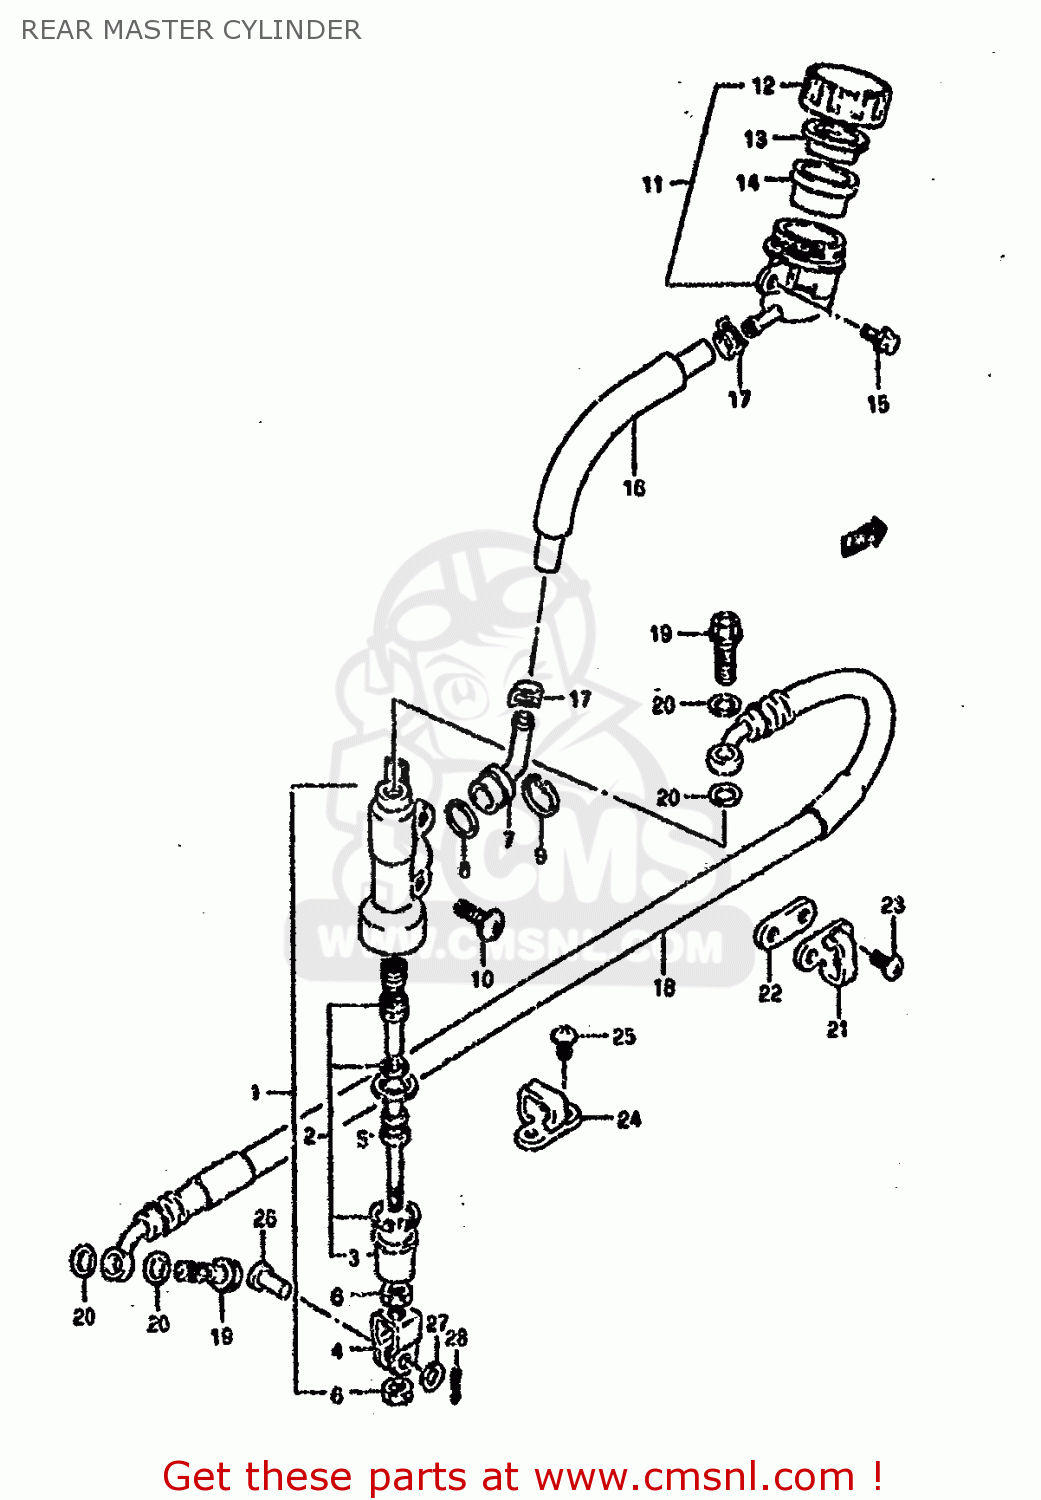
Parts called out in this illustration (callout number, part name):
1	CYLINDER ASSY,RR MASTER
2	PISTON/CUP SET
3	BOOT
4	YOKE
5	ROD,PUSH
6	NUT
7	CONNECTOR
8	O RING
9	CIRCLIP
10	SCREW(6X16)
11	TANK ASSY,RR BRAKE RESERVOIR
12	CAP
13	PLATE
14	DIAPHRAGM
15	BOLT
16	HOSE,TANK
17	CLAMP,RESERVOIR HOSE
18	HOSE,REAR BRAKE
19	BOLT UNION
20	WASHER(10X15X1.5)
21	GUIDE,RR BRAKE HOSE
22	SEAT,RR BRAKE HOSE GUIDE
23	SCREW
24	GUIDE,RR BRAKE HOSE
25	SCREW
26	PIN(8X20)
27	WASHER(8.5X13X1.6)
28	PIN
